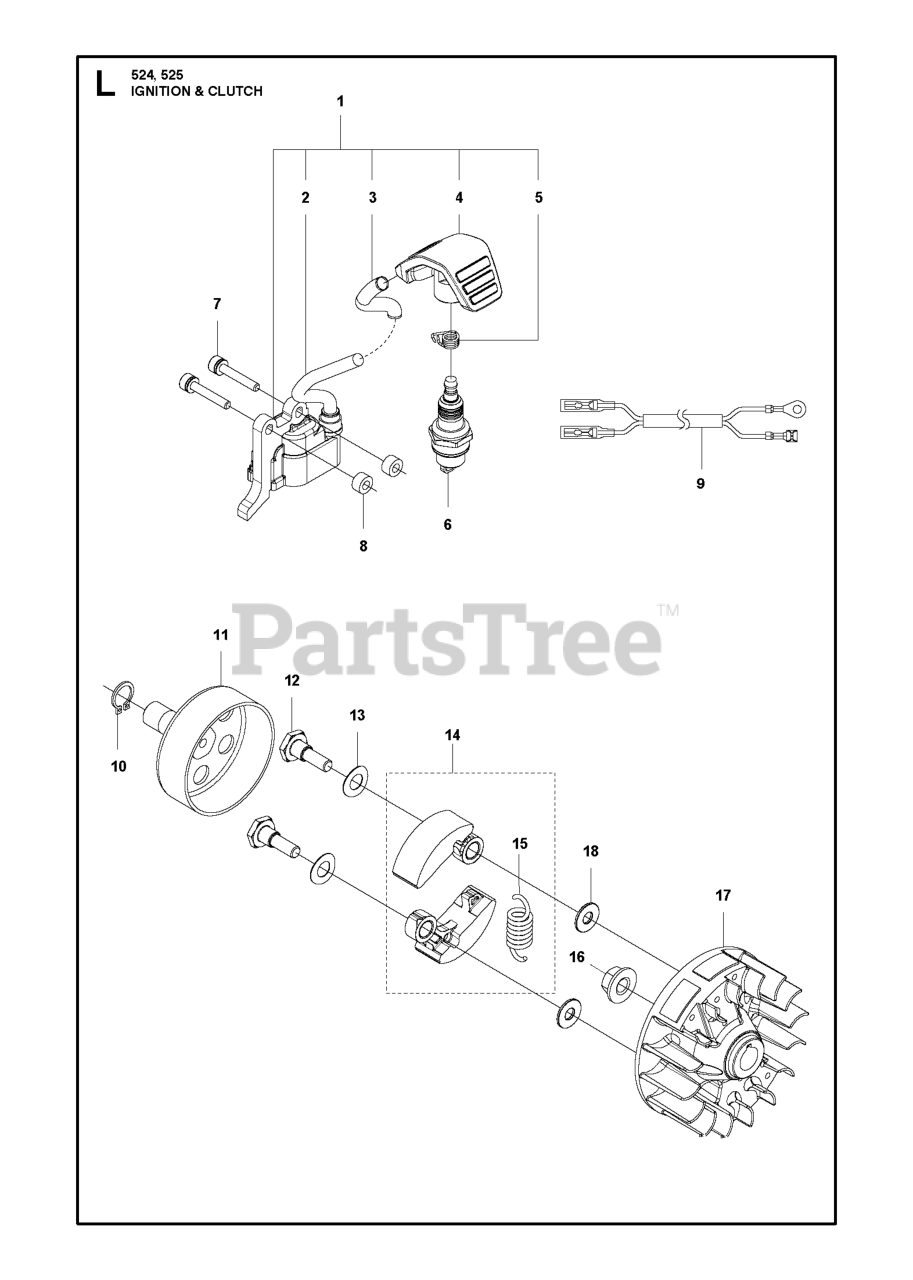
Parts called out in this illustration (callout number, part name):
1	IGNITION COIL ASSY
2	IGNITION CABLE
4	SPARK PLUG CAP
6	SPARK PLUG HQT-2 RESISTOR
7	BOLT M4 X 25
9	SHORT CIRCUIT CABLE
11	CLUTCH DRUM
14	CLUTCH ASSY
15	CLUTCH SPRING
16	NUT
